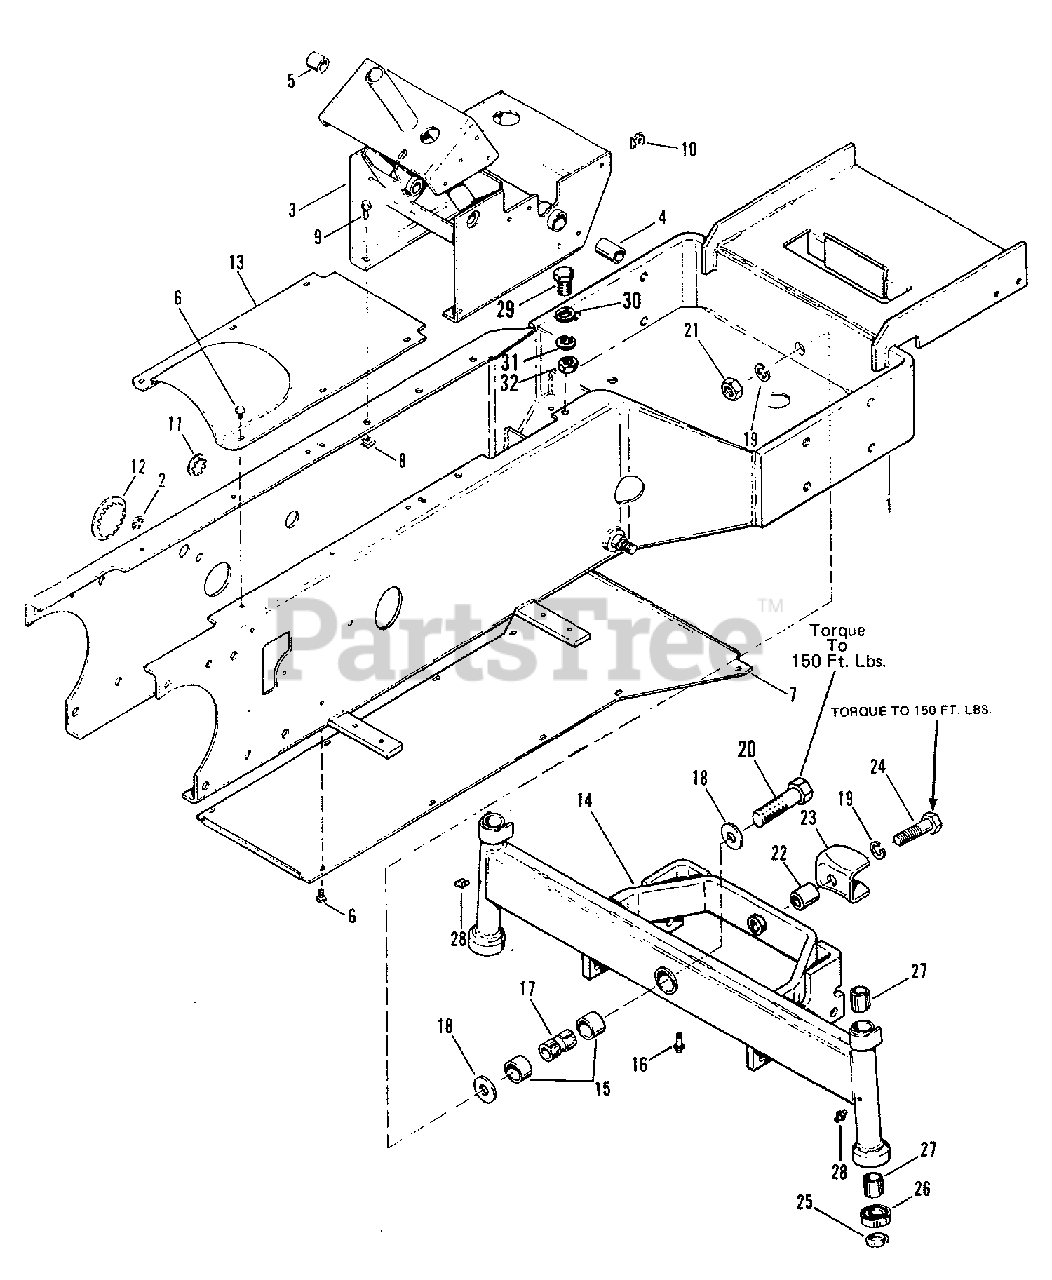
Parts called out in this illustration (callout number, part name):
1	FRAME ASSEMBLY
2	PLUG, Hole
3	SUPPORT ASSEMBLY
5	BEARING, Sleeve
6	SCREW, Washer Head Taptite, 1/4"-20 x 3/8" Lg
7	COVER, Bottom
8	NUT, Clip
9	SCREW, Washer Head
10	NUT, Speed
11	PLUG, Hole
12	PLUG, Hole
13	COVER, Top
14	AXLE ASSEMBLY
16	FITTING, Grease
17	SPACER, Axle
18	WASHER, Thrust
19	LOCKWASHER, 5/8"
20	CAPSCREW, Hex, 5/8"-11 x 3-1/2" Lg.
21	NUT, Hex, Full, 5/8"-11
24	SCREW, 5/8"-11 x 2-1/4" Lg.
25	SPACER, Bearing
26	BEARING, Thrust
27	BUSHING, Spindle
28	FITTING, Grease
29	CAPSCREW, Hex, 5/16"-3/4" Lg. Gr.2
30	WASHER, Flat, 5/16
31	LOCKWASHER, 5/16
32	NUT, Hex, 5/16
